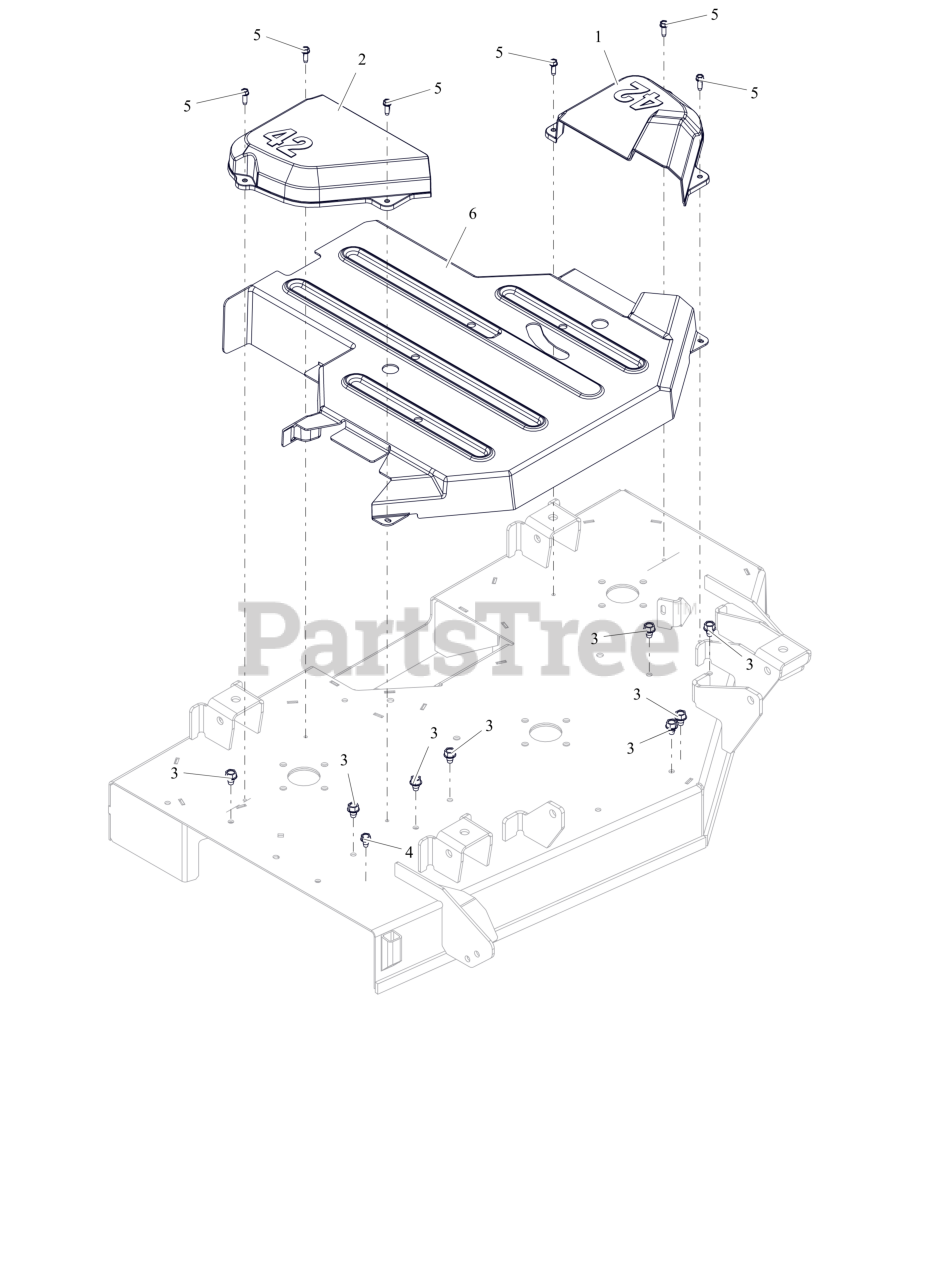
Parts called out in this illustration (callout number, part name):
1	COVER, BELT 42" LH
2	COVER, BELT 42" RH
3	SCR,TAP .375-16X.50 HWH TR ZCC
4	SCR,TAP .312-18X.50 HWH TR ZCC
5	SCR,TAP .25-20X.75 HWH TR ZCC
6	GUARD, IKON BELT-42" CE
